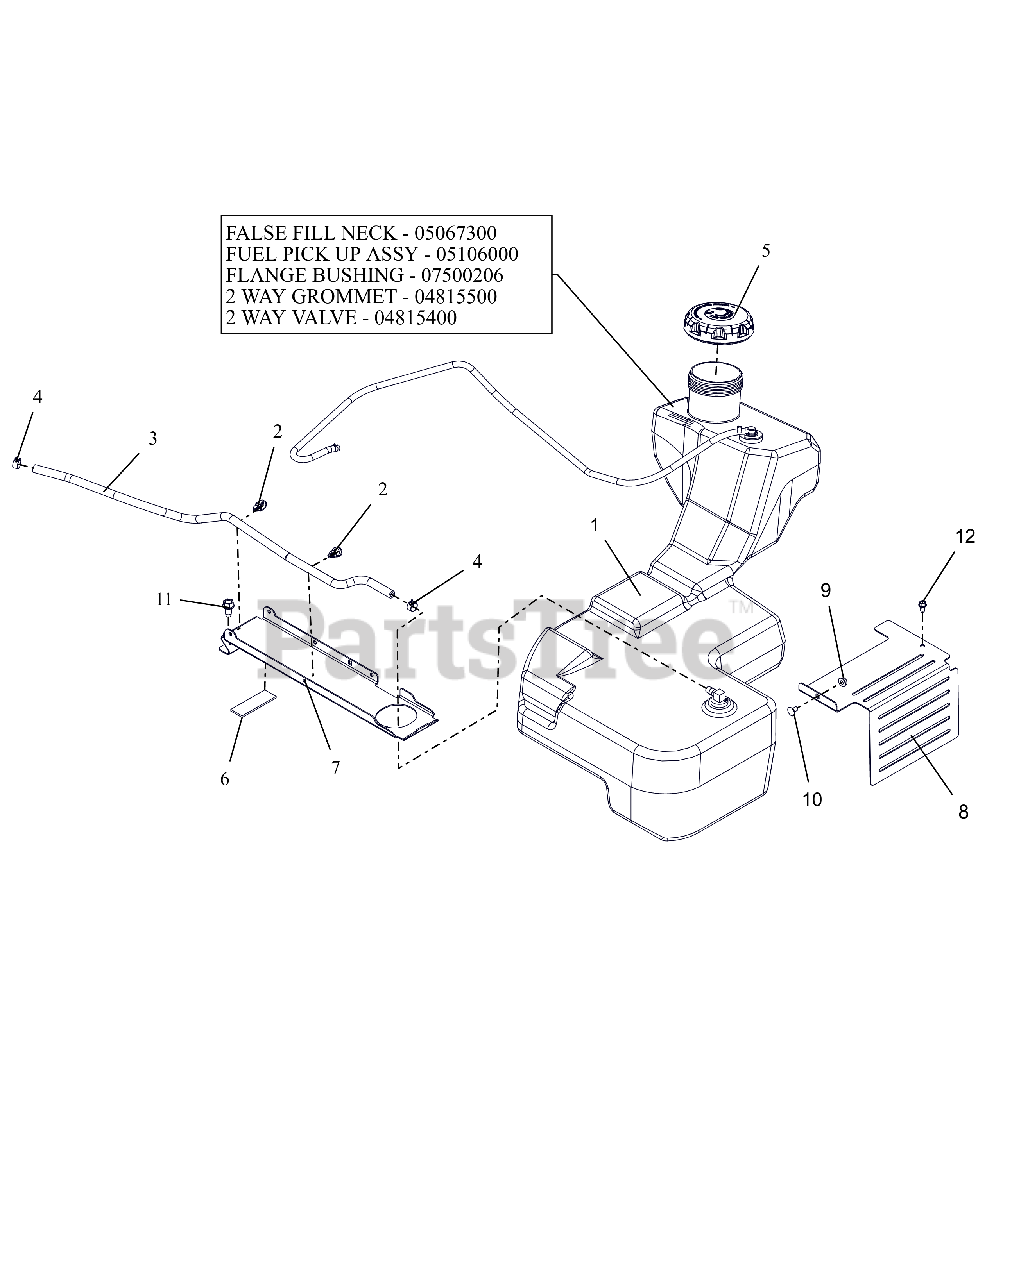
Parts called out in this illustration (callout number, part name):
1	ASM, FUEL TANK-HD
1	INSERT, FUEL NECK FALSE FILL
1	ASM, HD FUEL PICK-UP
1	BSHG-FLG .375X1.062X.625 NITR
1	GROMMET, 2-WAY
1	VALVE, 2-WAY
2	ROUTING CLIP (1/2" ID)
3	HOSE, .25 LOW-PERM BULK GAS
4	CLAMP, FUEL LINE
5	CAP, FUEL VENTIN AUTOLOCK
6	PAD,RBR 1.0"X3.0" W/ADHESIVE
7	BRKT, FUEL TANK HOLD DOWN
8	GUARD, TRANSAXLE FAN LH (BLACK)
9	NUT-LK-CTR-FLG .25-20 ZC120
10	BLT, RHSSN.25-20X.500 G5 ZCC
11	SCR,TAP .375-16X.75 HWH TR ZCC
12	SCR-TAP .25-20X.50 HWH ZCC
